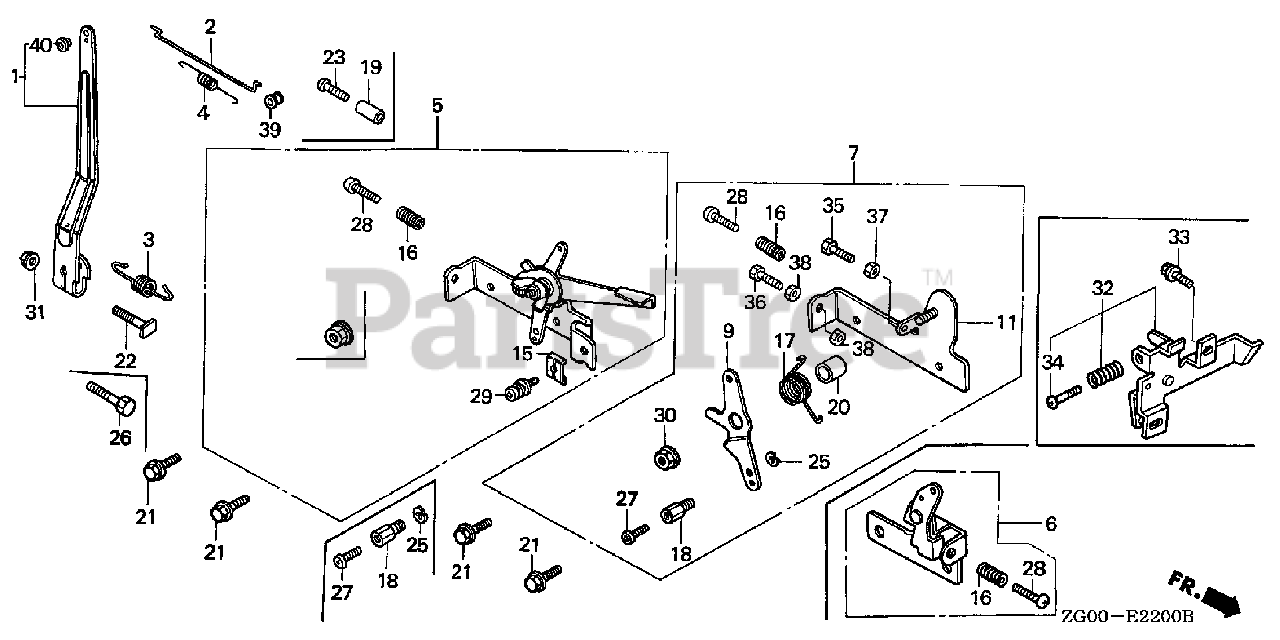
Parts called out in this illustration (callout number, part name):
1	ARM, GOVERNOR (NOT AVAILABLE)
2	ROD, GOVERNOR (NOT AVAILABLE)
3	SPRING, GOVERNOR (NOT AVAILABLE)
4	SPRING, THROTTLE RETURN
5	CONTROL ASSY. Use from Engine SN 1443596.
5	CONTROL ASSY. Use up to Engine SN 1023549.
5	CONTROL ASSY.
15	HOLDER, CABLE
16	SPRING, CONTROL ADJUSTING
21	BOLT, FLANGE (6X12)
22	BOLT, GOVERNOR ARM
28	SCREW, PAN (5X20) Use from Engine SN 1443596.
28	SCREW, PAN (5X25)
29	SCREW-WASHER (5X16)
30	NUT, FLANGE (6MM)
31	NUT, FLANGE (6MM)
